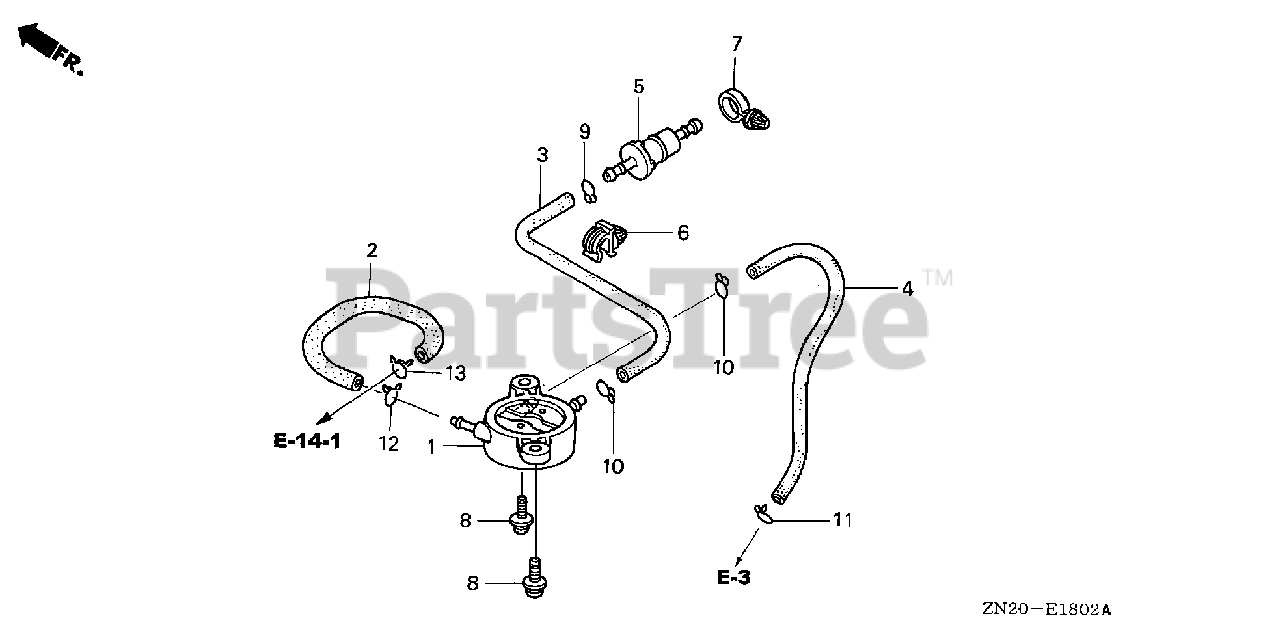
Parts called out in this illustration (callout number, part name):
1	PUMP ASSY., FUEL
2	TUBE, FUEL
3	TUBE B, FUEL
4	TUBE, DIAPHRAGM
5	STRAINER, FUEL
6	CLAMP, WIRE
7	CLIP, WIRE HARNESS
8	SCREW-WASHER (6X16)
9	CLIP, TUBE (B8)
10	CLIP, TUBE (B10)
11	CLIP, TUBE (C9)
12	CLIP, TUBE (C11)
13	CLIP, TUBE (B10)
13	CLIP, TUBE (C11)
